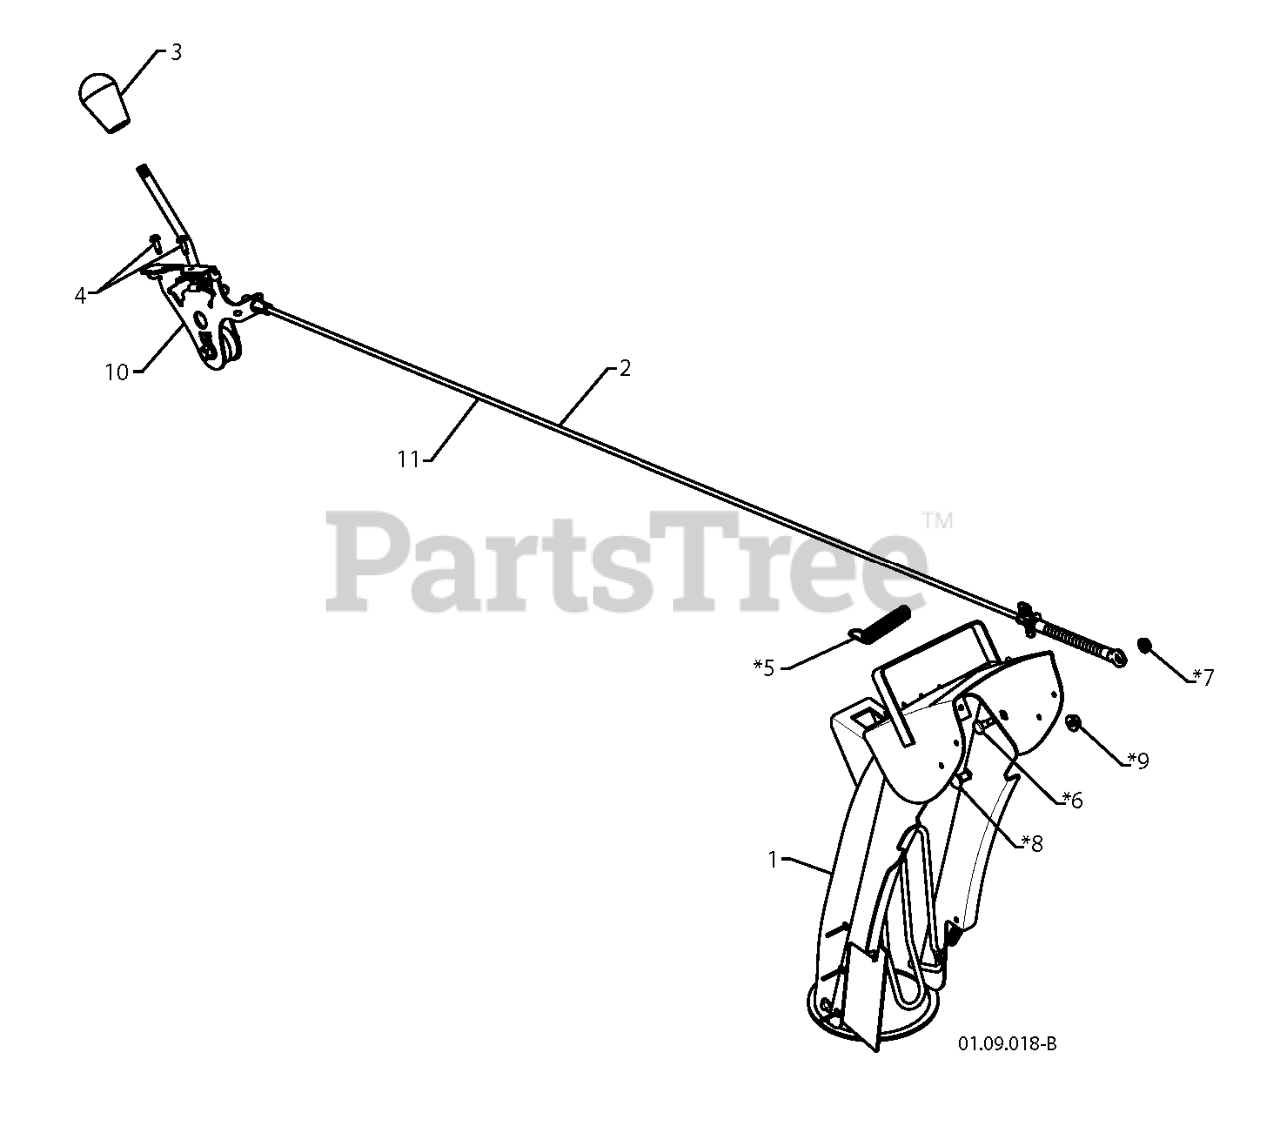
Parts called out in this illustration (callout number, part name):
2	CONTROL.ASM.DEFLECTOR
3	KNOB LEVER, BLACK
4	SCREW #10-24 X 5/8
10	RP CNTRL.HEAD.ASSEM.DEFLECTOR
11	SERVICE.CHUTE.DEF.CBL.GRY
